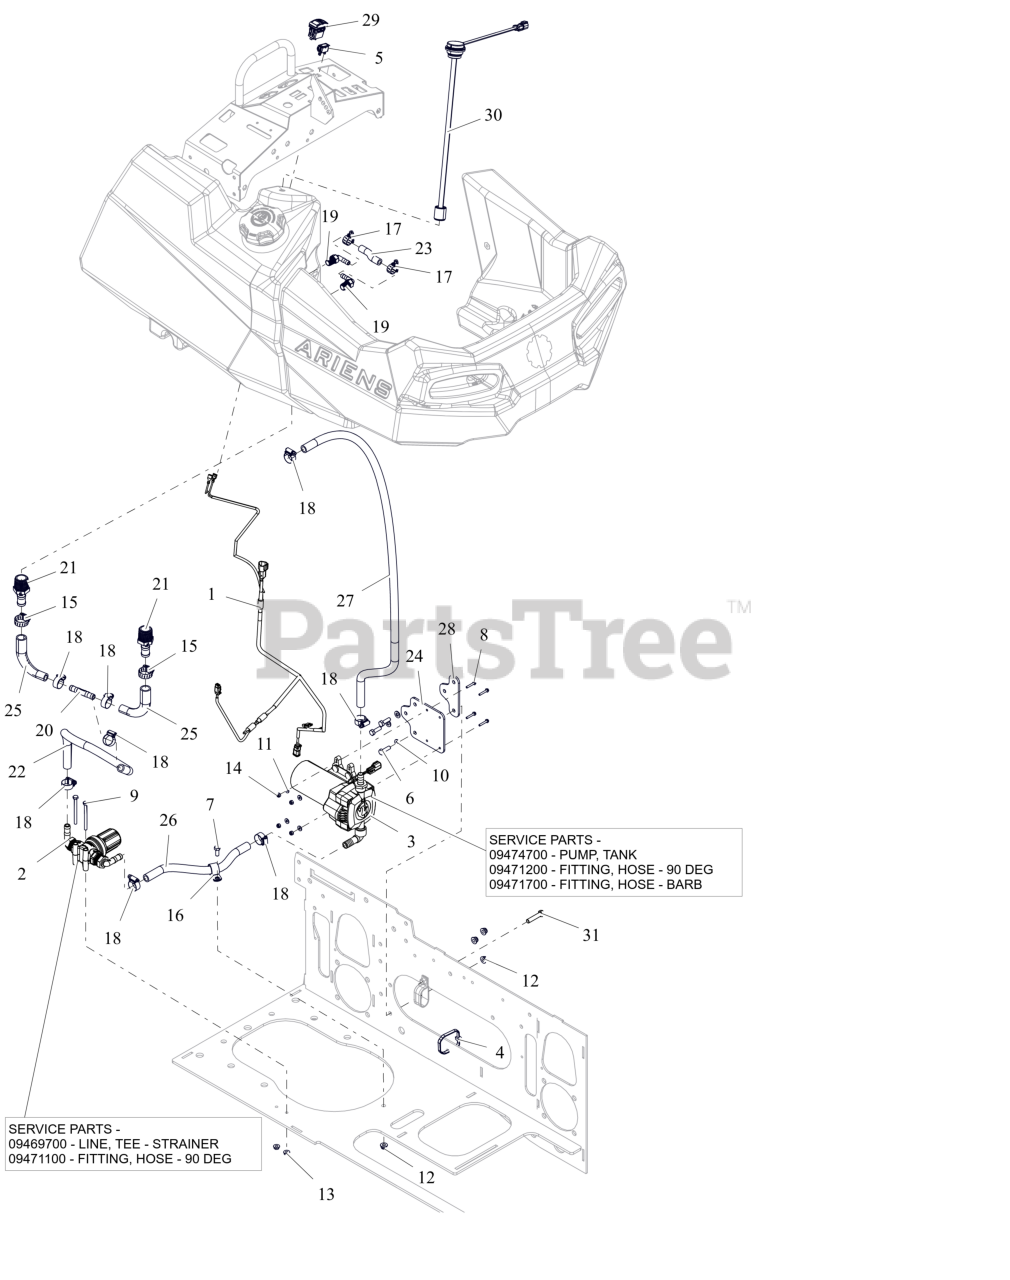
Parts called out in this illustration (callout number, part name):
1	HARNESS- BRINE KIT
2	LINE-TEE - STRAINER ASM
2	LINE, TEE - STRAINER
2	FITTING- HOSE 3/4NPTX1/2 90DEG
3	ASM- PUMP
3	PUMP-TANK- SPRAY SYSTEM
3	FITTING-HOSE 90 1/2"FNPTX1/2"
3	FITTING-HOSE 1/2FNPT X1/2 BARB
5	LIGHT, INDICATOR (RED)
6	BLT,HEX .31-18X1.00 G5 ZCC
7	BLT,HEX .31-18X.75 G5 ZCC
8	SCR, HWH #8-32X1.00 ZCC
9	BLT-HEX .25-20X3.00 G5 ZCC
10	WSHR,FLT .344X.688X.065 ZCC
11	WSHR,FLT .196X.500X.066 ZCC
12	NUT,LK-NYL-FLG .31-18 G5ZC120
13	NUT-LK-CTR-FLG .25-20 ZC120
14	NUT, NYL LK #8-32 ZCC
15	CLAMP, HOSE - #12 SAE
16	CLAMP, COUSHIONED STEEL REV
17	CLAMP-HOSE WRM .44/.78X.53 F06
18	CLAMP,.88 DIA. HOSE
19	FITTING-HOSE-90 3/8MNPT X 3/8B
20	HOSE- TEE BARB .50X.50X.50
21	FITTING-HOSE-1"MNPTX3/4" BARB
22	HOSE-.50X.75X17.75
23	HOSE-.375X.625X3.50
24	BRKT- PUMP BRINE TANK
25	HOSE-MOLDED REDUCTION .50X.75
26	HOSE-.50X.75X12.00
27	HOSE-.50X.75X39.50
28	BRKT- PUMP SPACER
29	SWITCH- ROCKER - ON-OFF-NO
30	SENDER- TANK - BRINE
31	BLT, HEX .38-16X1.75 G5 ZCC
